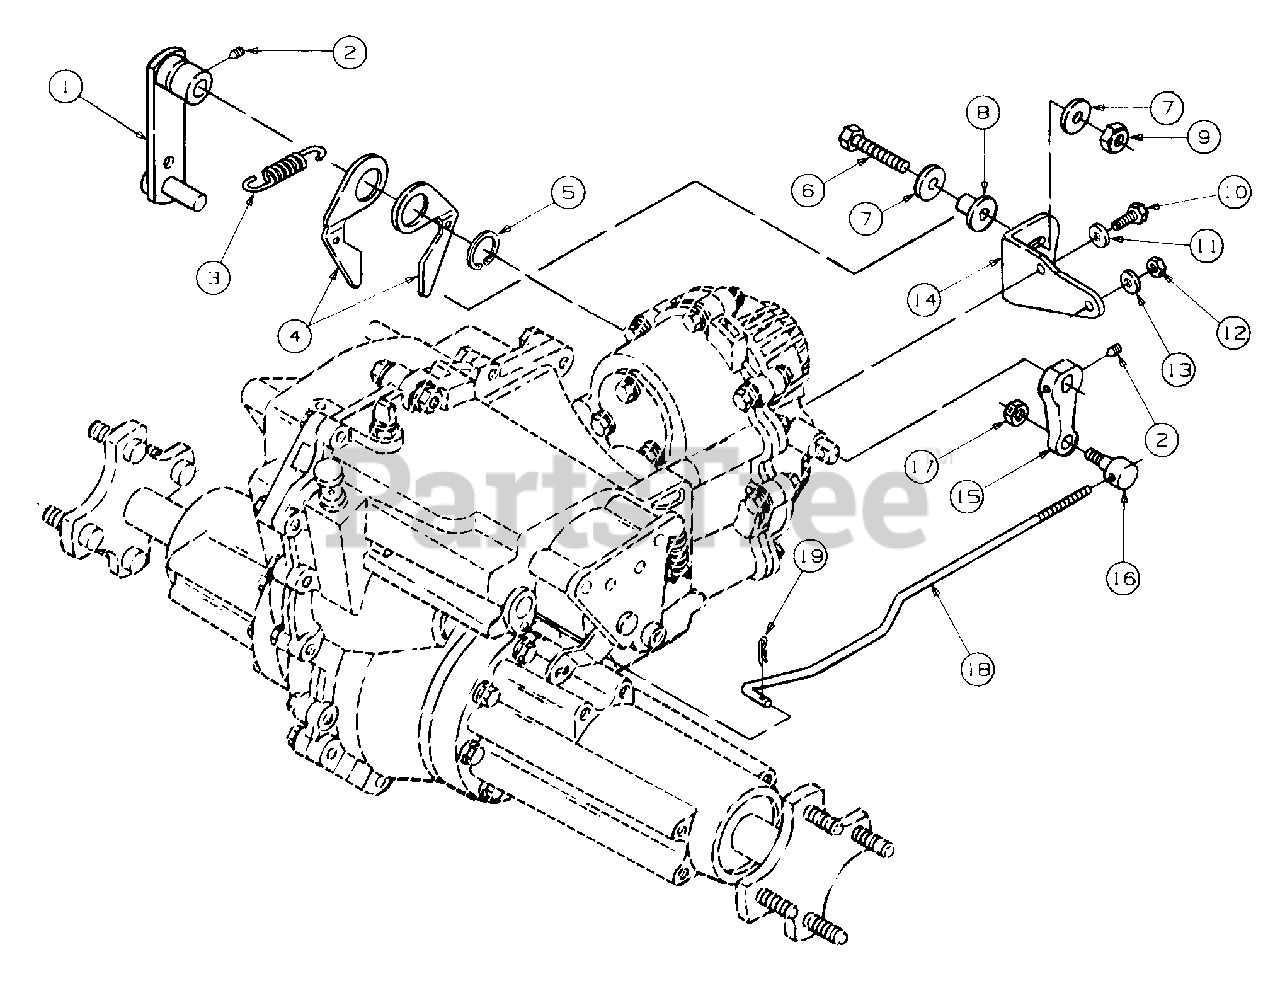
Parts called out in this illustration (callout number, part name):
1	Arm Assy, Control
2	Screw w/Patch, Set
3	Spring, Extension, .477 OD x 1.68 Lg
4	Arm, Neutral
5	Ring, Snap, .875 Shaft
6	Screw, Hex Cap, 1/4-20 x 1.25 Lg
7	Washer, Flat, .25 x .93 x .120 Thk
8	Spacer, Centering
9	Nut, Hex Top Lock, 1/4-20
10	Screw, Hex Cap, 5/16-18 x 4.0 Lg
11	Washer, Lock, 5/16
12	Nut, Hex Top Lock, 1/4-20
13	Washer, Flat, .25 x .62 x .052 Thk
14	Bracket, 6-Speed Neutral
15	Arm, Clutch/Brake
17	Nut, Hex Center Lock Jam, 5/16-24
18	Rod, Shift Interlock
19	Pin, Internal Cotter
